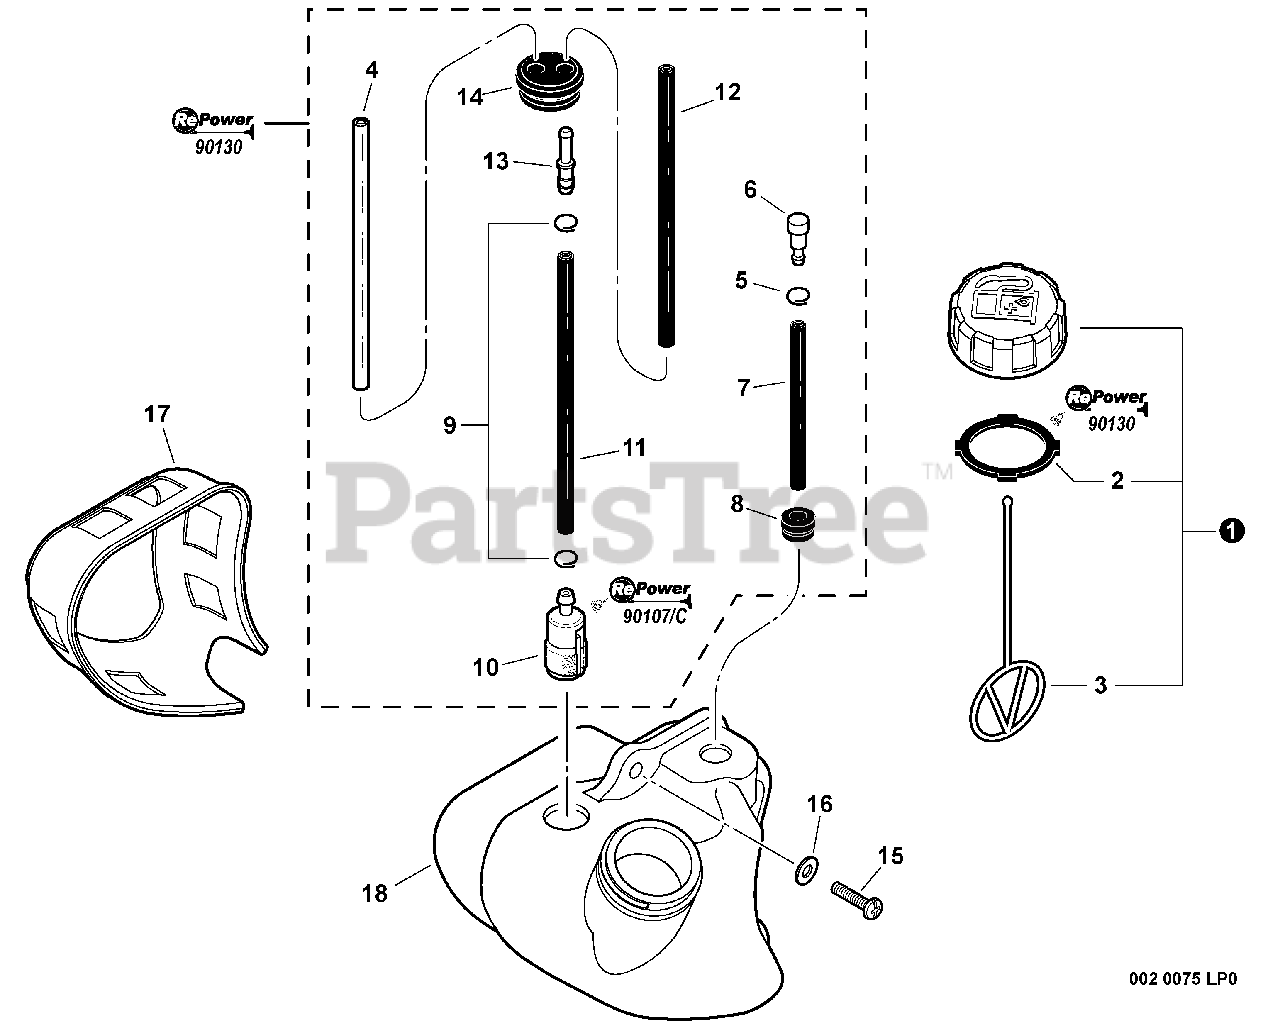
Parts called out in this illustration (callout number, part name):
1	CAP ASSY, FUEL
2	GASKET, FUEL CAP
3	CONNECTOR, CAP L= 100 MM
4	PIPE, FUEL 3×6×85 CLEAR
5	CLIP Ø6
6	VENT ASSY
7	PIPE, FUEL VENT 3×5×50
8	GROMMET
9	CLIP Ø6
10	FILTER, FUEL
11	PIPE, FUEL 3×5×90 BLACK
12	PIPE, FUEL 3×5×87 BLACK
13	CONNECTOR, PIPE Ø5ר3.5
14	GROMMET, FUEL
15	SCREW, TAPPING 5×20
16	WASHER 5.5×12×0.8
17	GUARD, FUEL TANK
18	TANK, FUEL
19	FUEL SYSTEM KIT
20	TUNE-UP KIT - REPOWER
